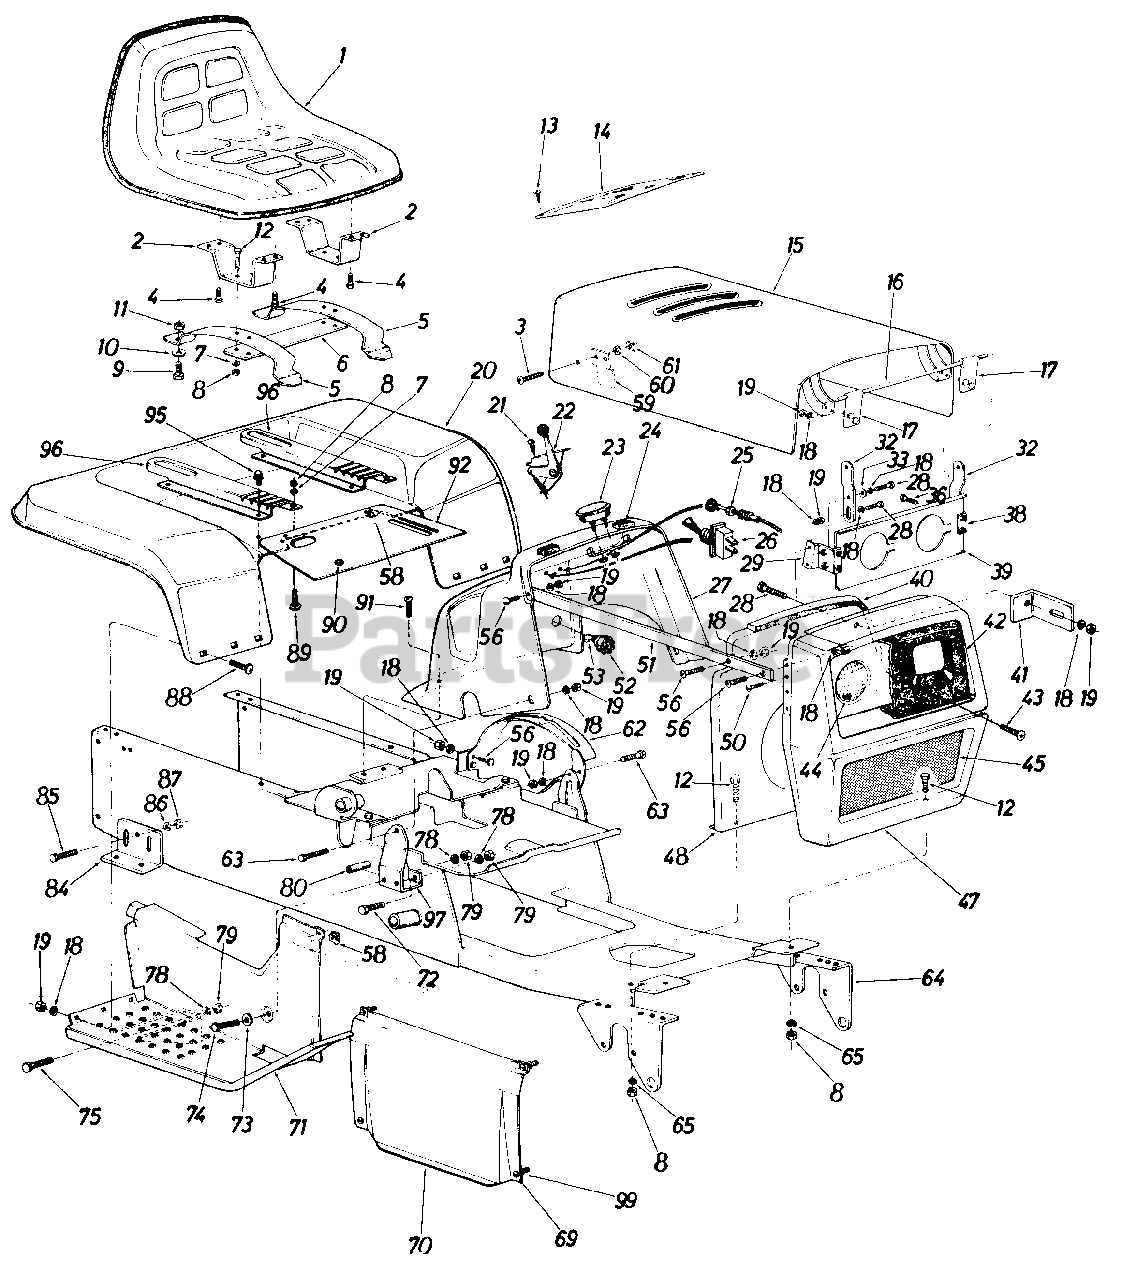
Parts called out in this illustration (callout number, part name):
1	Seat Ass'y. Comp.
2	Seat Support Brkt.
3	Truss Hd. Mach. Scr. #10-24 x.38" Lg.
4	Hex Wash. Hd. Self-Tap Scr. 3/8-16 x .75" Lg.
7	L-Wash. 5/16" Scr.*
8	Hex Nut 5/16-18 Thd.*
9	Nylon Scr. 1/2-13 x .75" Lg.
10	Fl-Wash. .531 I.D. x .930 O.D.
11	Hex Cent. L-Nut 1/2-13 Thd.
12	Hex Scr. 5/16-18 x .75" Lg.*
13	Self-Tap Oval Hd. Scr. 1/2" Lg.
14	Dash Panel Cover
15	Hood Ass'y.
16	Hinge Rod
17	Hood Hinge Ass'y.
18	L-Wash. 1/4" Scr.*
19	Hex Nut 1/4-20 Thd.*
20	Rear Fender
21	Fl-Hd. Truss Scr. #10 x .62" Lg.
22	Throttle Control
23	Ammeter
24	Rubber Bumper
25	Choke Control
26	Light Switch
27	Dash Panel
28	Hex Scr. 1/4-20 x .62" Lg.*
29	Hood Support Brkt. Ass 'y.-R. H .
36	Hex Scr. 1/4-20 x .38" Lg.*
38	Hood Support Brkt. Ass'y.-L. H .
41	Heat Shield Brkt.
42	Head Lamp Bezel
43	Truss Mach. Scr. #10-24 x .50" Lg.
44	Head Lamp
45	Grille Screen
50	Truss Mach. Scr. 1/4-20 x .75" Lg.
51	Grille Strap
52	Ignition Switch
53	Ignition Key
56	Hex Scr. 1/4-20 x .75" Lg.
58	Clip-On Receptacle
59	Hood Spring
60	L-Wash. #10
61	Hex Nut #10-24
62	Speed Control Guide
63	Truss Mach. Scr. 1/4-20 x .75 " Lg .
64	Frame Ass'y.
65	Bell-Wash. 5/16" Scr.
69	1/4-Turn Stud
70	Hood Lower Side Panel
71	Foot Step Panel Ass'y.- R. H .
72	Hex Scr. 3/8-16 x 1.00" Lg. Grade 5
73	Fl-Wash. .385 I.D. x .62 O.D.
74	Hex Scr. 3/8-16 x 3.00" Lg.
75	Hex Scr. 3/8-16 x 1.00" Lg. Grade 5
78	L-Wash. 3/8" Scr.
79	Hex Nut 3/8-16 Thd.
80	Spacer .375 I.D. x .62 O.D. x 2.00" Lg.
84	Transaxle Support Brkt.
85	Rd. Hd. Rib Neck Scr. 3/8-24
86	L-Wash. 3/8" Scr.
87	Hex Nut 3/8-24 Thd.*
88	Carr. Bolt 1/4-20 x .50" Lg.
89	Carr. Bolt 5/16-18 x .62" Lg.
90	Snap Bushing
91	Fl-Hd. Self-Tap Scr. 1/4-20 x .62" Lg.
96	Seat Adjustment Brk.
